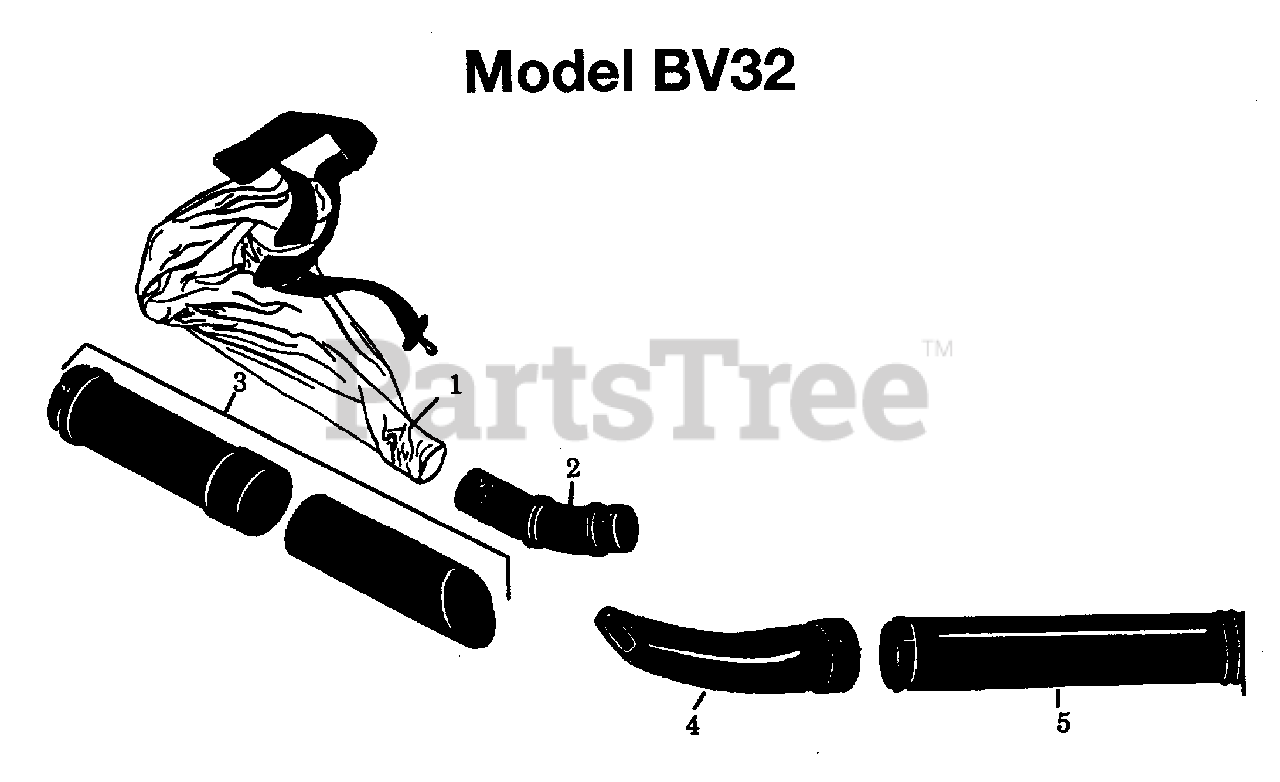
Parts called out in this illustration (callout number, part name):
1	COLLECTION BAG W/ STRAP
2	ELBOW TUBE
3	VAC TUBE SET
4	NOZZLE-BLOWER (FLARE)
5	TUBE-BLOWER (UPPER)
